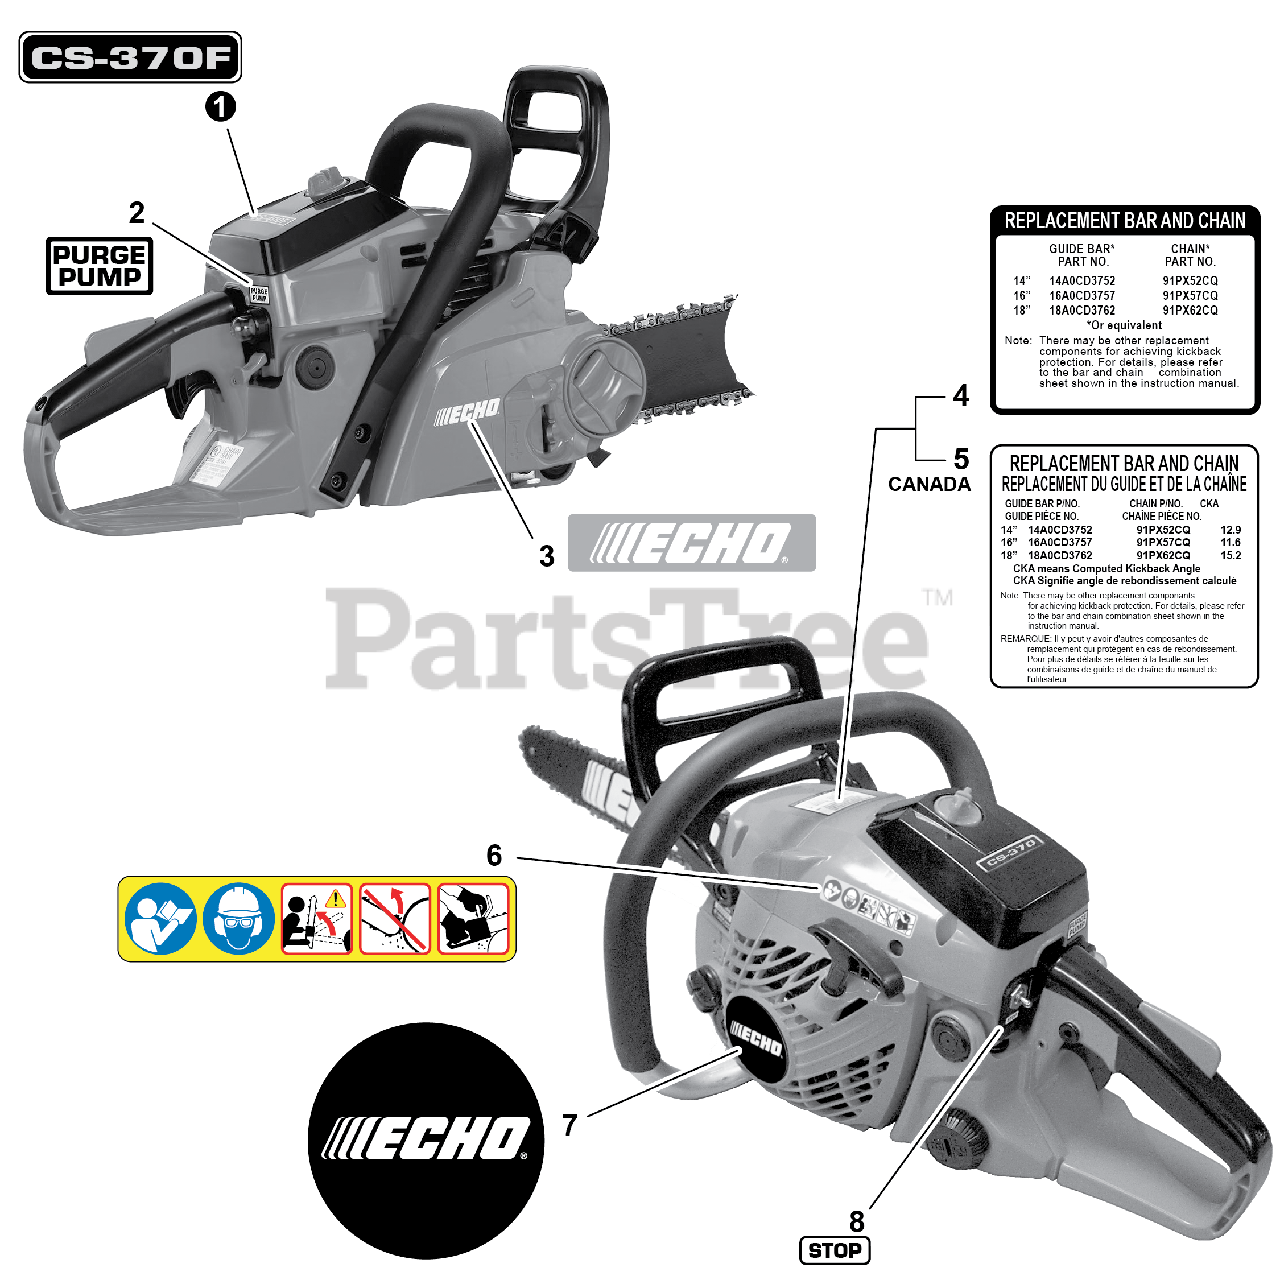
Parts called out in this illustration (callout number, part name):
1	LABEL - MODEL CS-370F
2	LABEL, PURGE PUMP
3	LABEL, ECHO
4	LABEL, BAR & CHAIN
5	LABEL, BAR & CHAIN - CANADA
6	LABEL, CAUTION
7	LABEL, ECHO
8	LABEL, STOP
